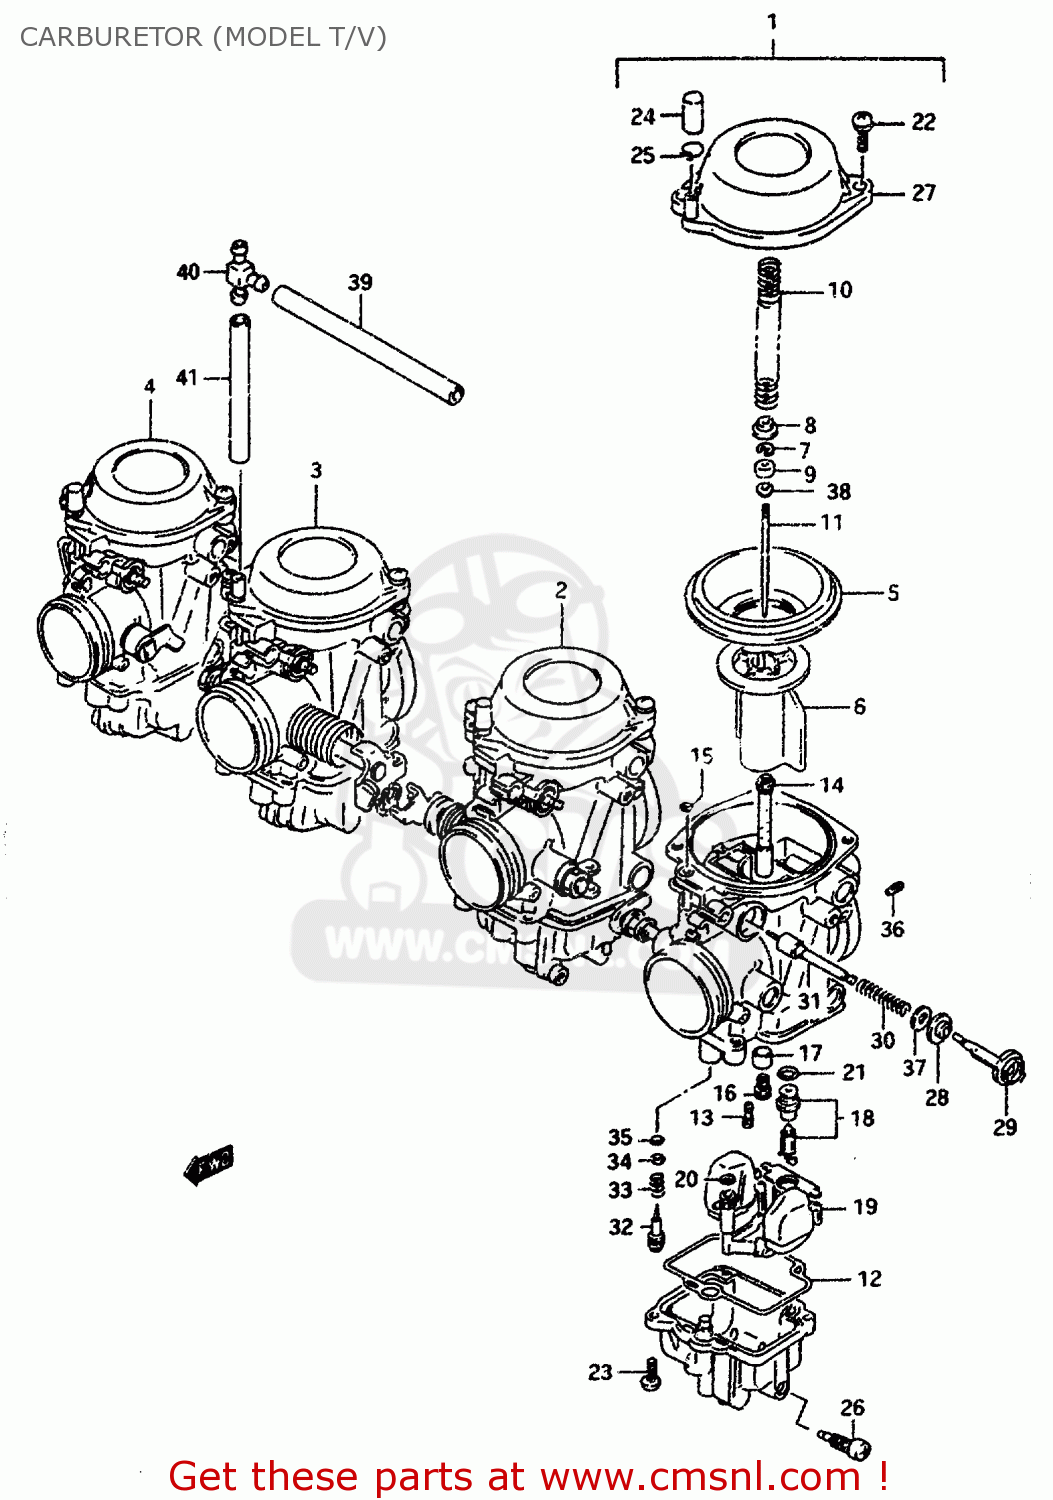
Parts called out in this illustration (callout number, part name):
1	CARBURETOR ASSY, LH
2	CARBURETOR ASSY, ML
3	CARBURETOR ASSY, MR
4	CARBURETOR ASSY, RH
5	DIAPHRAGM
6	VALVE,PISTON
7	CLIP
8	RING
9	RING
10	SPRING
11	NEEDLE,JET
12	GASKET,FLOAT CHAMBER (NAS)
13	JET(40)
14	JET,NEEDLE(P-2)
15	O RING
16	JET,MAIN(122.5)
17	RING
18	VALVE ASSEMBLY,NEEDLE
19	FLOAT ASSY
20	O RING
21	O-RING,NEEDLE VALVE
22	SCREW
23	SCREW(5X14)
24	CAP
25	CLIP
26	SCREW,DRAIN
27	COVER, DIAPHRAGM
28	CAP,STARTER
29	HOLDER,GUIDE
30	SPRING
31	PLUNGER ASSY
32	SCREW,PILOT
33	SPRING
34	WASHER
35	O RING,PILOT AIR SCREW
36	JET,AIR(1.2)
37	WASHER
38	WASHER
39	HOSE(5X9X600)
40	NIPPLE
41	HOSE(5X9X600)
50	O RING,PILOT AIR SCREW
51	JET,AIR(1.2)
52	WASHER
53	WASHER
54	HOSE(5X9X600)
55	NIPPLE
56	HOSE(5X9X600)
